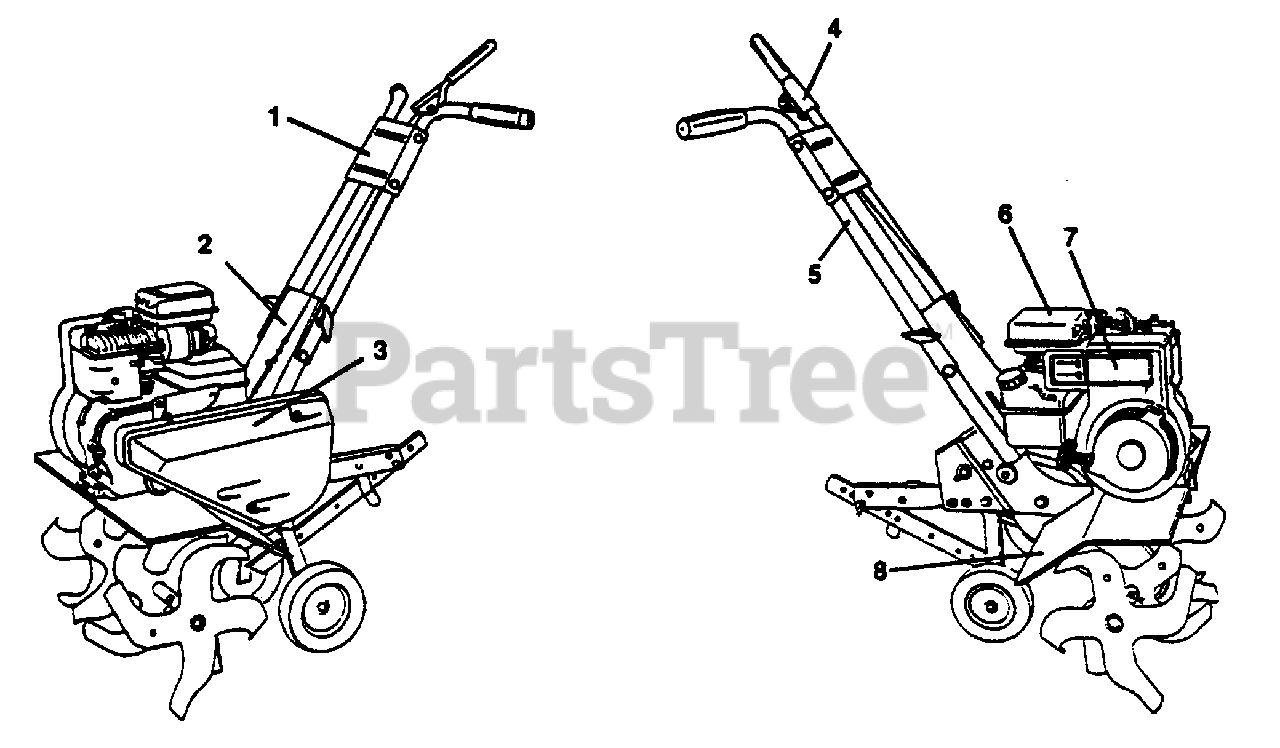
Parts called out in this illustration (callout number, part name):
1	Decal, Logo
2	Decal, HP (AYP part number)
3	Decal, Logo (AYP part number)
4	Decal, Tine Control (AYP part number)
5	Decal, Hand Placement (AYP part number)
6	Decal, Caution (AYP part number)
7	Decal, Briggs & Stratton (AYP part number)
8	Decal, Warning, Rotating Tines (AYP part number)
